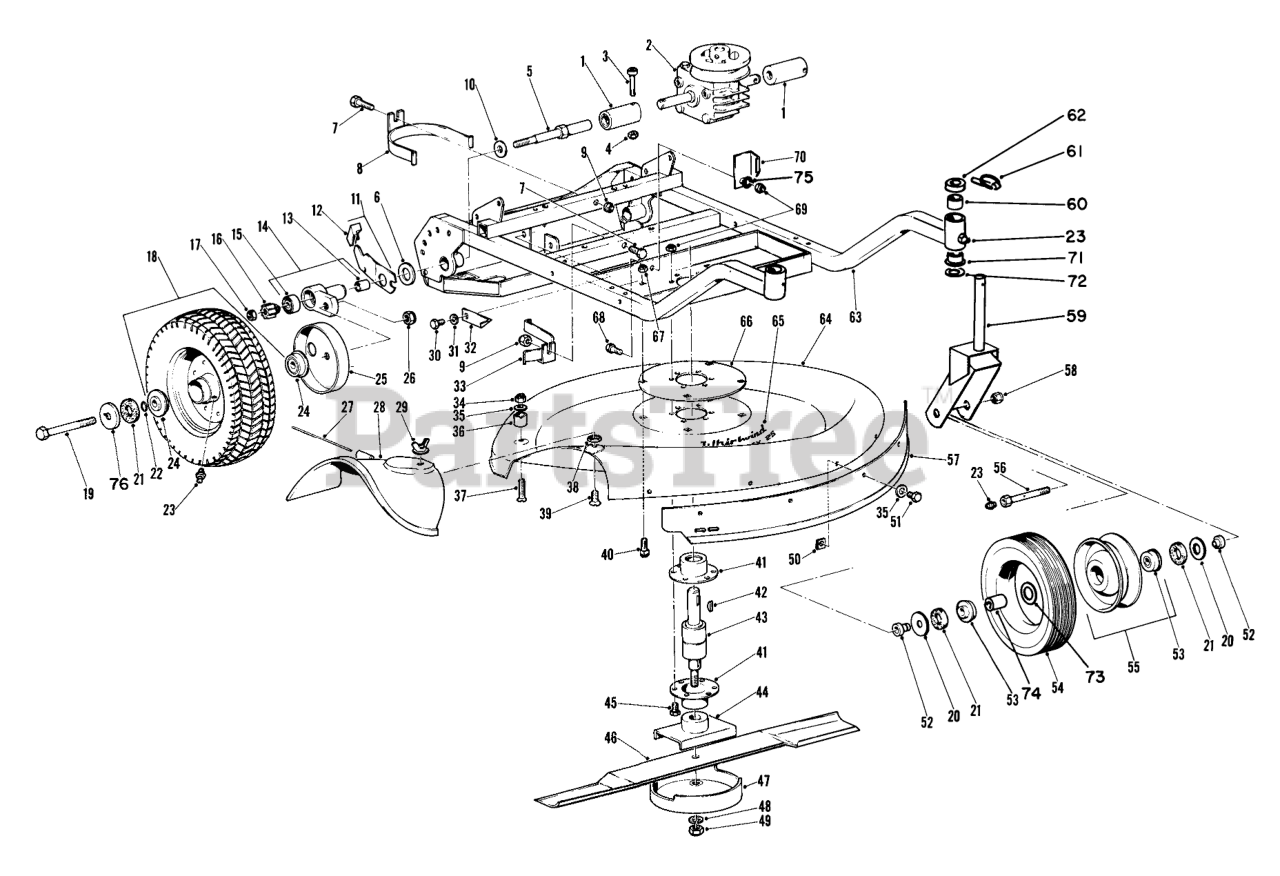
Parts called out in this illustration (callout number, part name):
1	Clutch Assy.
2	Transmission Assembly
3	DRIVE SCREW
4	NUT-LOCK, NI
5	DRIVE SPINDLE
6	Washer
7	SCREW-HH
8	Belt Retainer W.A.
9	NUT-LOCK, NI
10	Washer
11	RH SPRING ARM ASM
12	ARM KNOB
13	BUSHING
14	Pivot Arm
15	.375 RPP BALL BEARING
16	Pinion Kit
17	NUT-HJ
18	REAR WHEEL & TIRE ASM
19	SCREW-HH
20	WASHER-FLAT
21	Washer
22	O-RING
23	FITTING-GREASE
24	BEARING
25	Wheel Cover
26	NUT-LOCK, NI
27	Hinge Pin
28	DEFLECTOR
29	Nut Wing
30	SCREW-HH
31	WASHER-LOCK
32	Retainer
33	Belt Retainer W.A.
34	Nut
35	WASHER-FLAT
36	Spacer
37	Screw
38	PAL NUT
39	5/16-18X7/8 FLT HD MS
40	BOLT-CARR
41	BEARING HOUSING
42	KEY-WOODRUFF
43	Bearing Spindle
44	Retainer
45	SCREW-HH
46	Blade
48	WASHER-LOCK
49	NUT-HEX
50	SPEED NUT
51	SCREW-HH
52	CASTOR SPACER
53	BEARING-BALL
54	1.75-8 SEMIPNEU TIRE
55	Wheel W.A. w/Ref. No. 53
56	AXLE BOLT
57	Cover
58	NUT-HEX
59	CASTOR FORK WA RO
60	7/8 ID X 1.128 X 7/8 LG BSHG
61	PIN-LYNCH
62	HT OF CUT SPACER
63	Frame W.A.
64	Housing
65	Decal
66	Plate
67	NUT-HEX
68	SCREW-HH
69	Nut
70	Belt Retainer
71	FLANGE BUSHING
72	WASHER
73	WASHER-SPECIAL
74	BRG SPACER
75	WASHER-PLAIN
76	SLINGER
